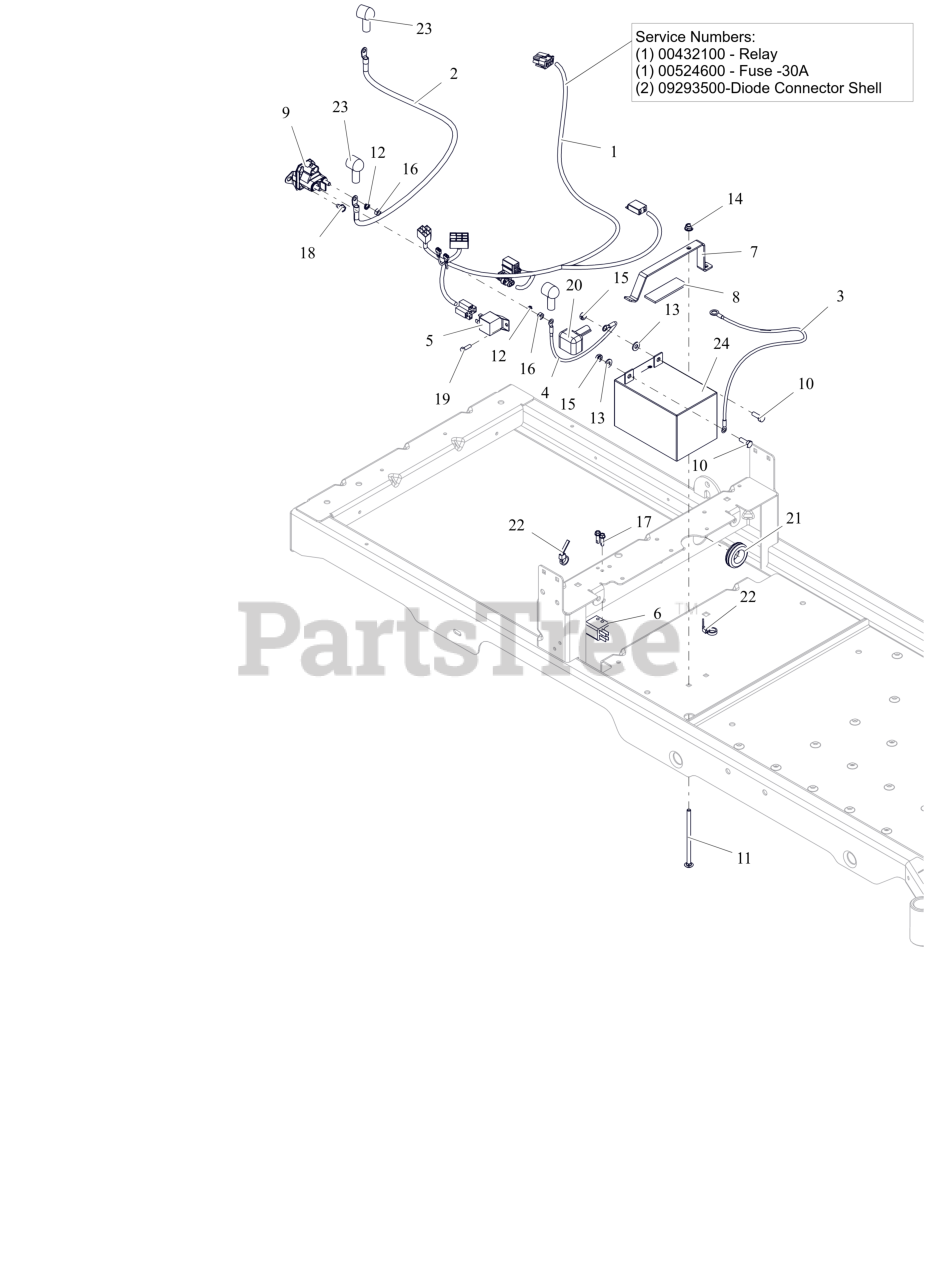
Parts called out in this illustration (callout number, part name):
1	HARNESS, ZOOM / ZT WIRE
1	RELAY,SEALED W/DIODE
1	FUSE, 30 AMP.
1	DIODE, CONNECTOR SHELL
2	CABLE,POS W/(2)1/4 RING 21.5LG
3	CABLE, NEGATIVE 26" 6 GA.
4	CABLE,POS W/2 1/4 RING 15.0 LG
5	RELAY,SEALED W/DIODE
6	SWITCH- DOUBLE POLE N.O./N.O.
7	HOLDDOWN, BATTERY, U1&190CCA
8	PAD,RBR 1.0"X3.0" W/ADHESIVE
9	SOLENOID, STARTER (SEALED)
10	BLT, HEX .25-20X.75 G5 ZCC
11	BLT, RHSN .25-20X4.50 G5 ZCC
12	WSHR,LK-EXT.262X.502X.026 ZCC
13	WSHR,FLT .281X.625X.065 ZCC
14	NUT,NYL-FLG .25-20 GF ZCC
15	NUT-KEPS .250-20 ZCC
16	NUT-STD M6-1.0 ZCC
17	SCR- 12-14X.75 HX W/HD TEK ZC
18	SCR,TAP .25-20X.375 HWH TR ZCC
19	SCR, SELF DRILLING 4.8 X 16 HEX HD
20	INSULATOR
21	GROMMET 1.0ID X 1.38 OD
22	CABLE TIE LG 5-1/2
23	BOOT, EYELET TERMINAL
24	BATTERY, FP12120 12V 12AH LUG STYLE ZTR
